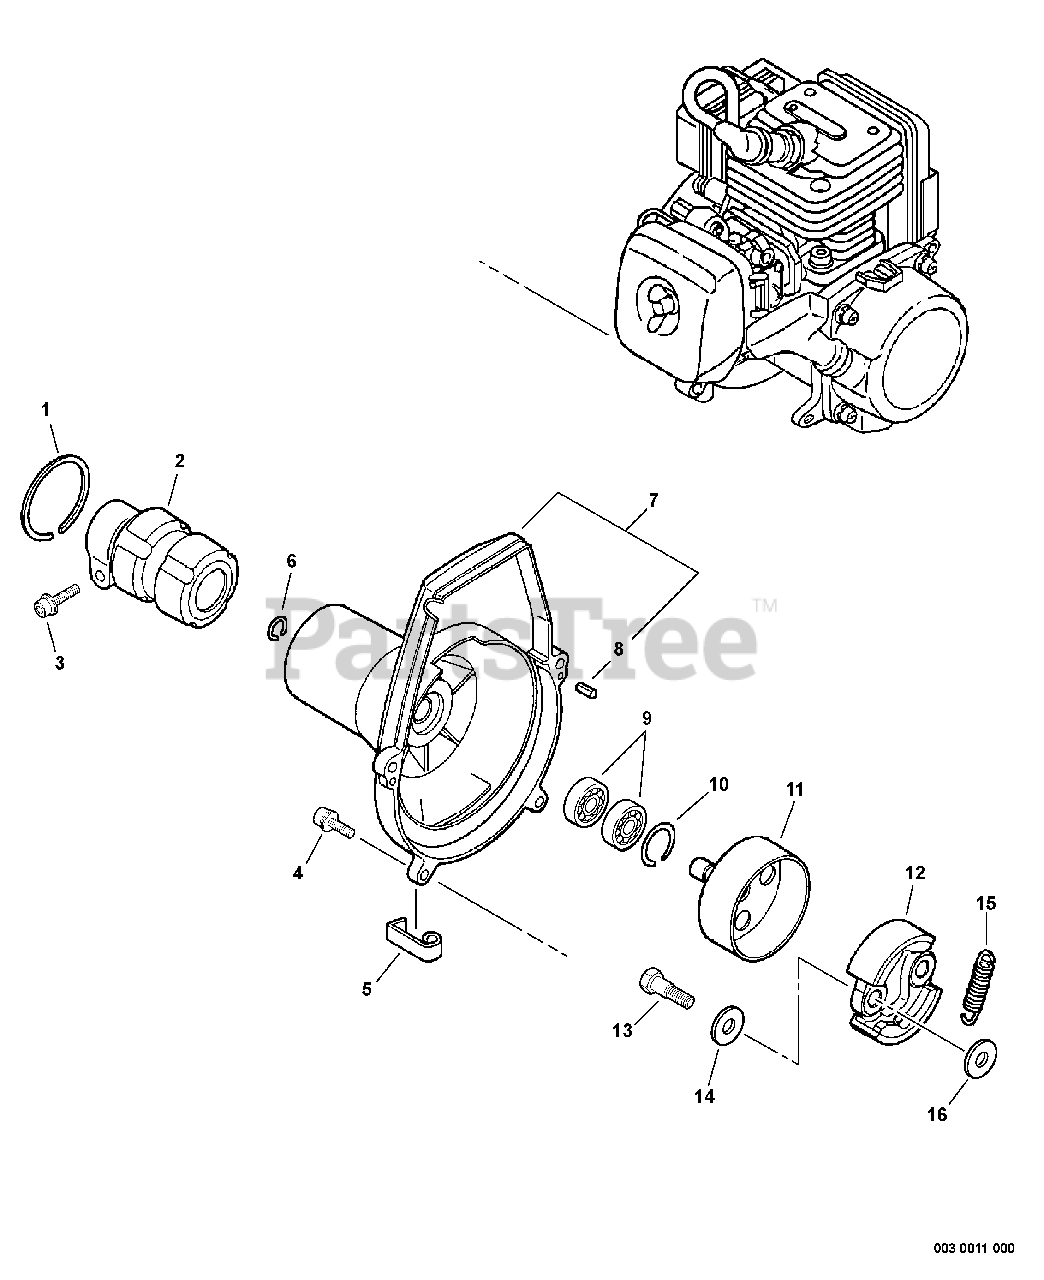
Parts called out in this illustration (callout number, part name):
1	RING, SNAP Ø42
2	HOLDER, MAIN PIPE
3	BOLT 5×28
4	BOLT 5×18
6	RING, RETAINING - 12
7	FAN CASE ASSY - ORANGE
8	PIN, LOCATING 4
9	BEARING, BALL 6001
10	RING, SNAP 28
11	DRUM, CLUTCH
12	SHOE, CLUTCH
13	BOLT, CLUTCH 8×7.9×M6
14	WASHER, SPRING 8.5×16×0.5
15	SPRING, CLUTCH
16	WASHER 6.2×19×1.0
